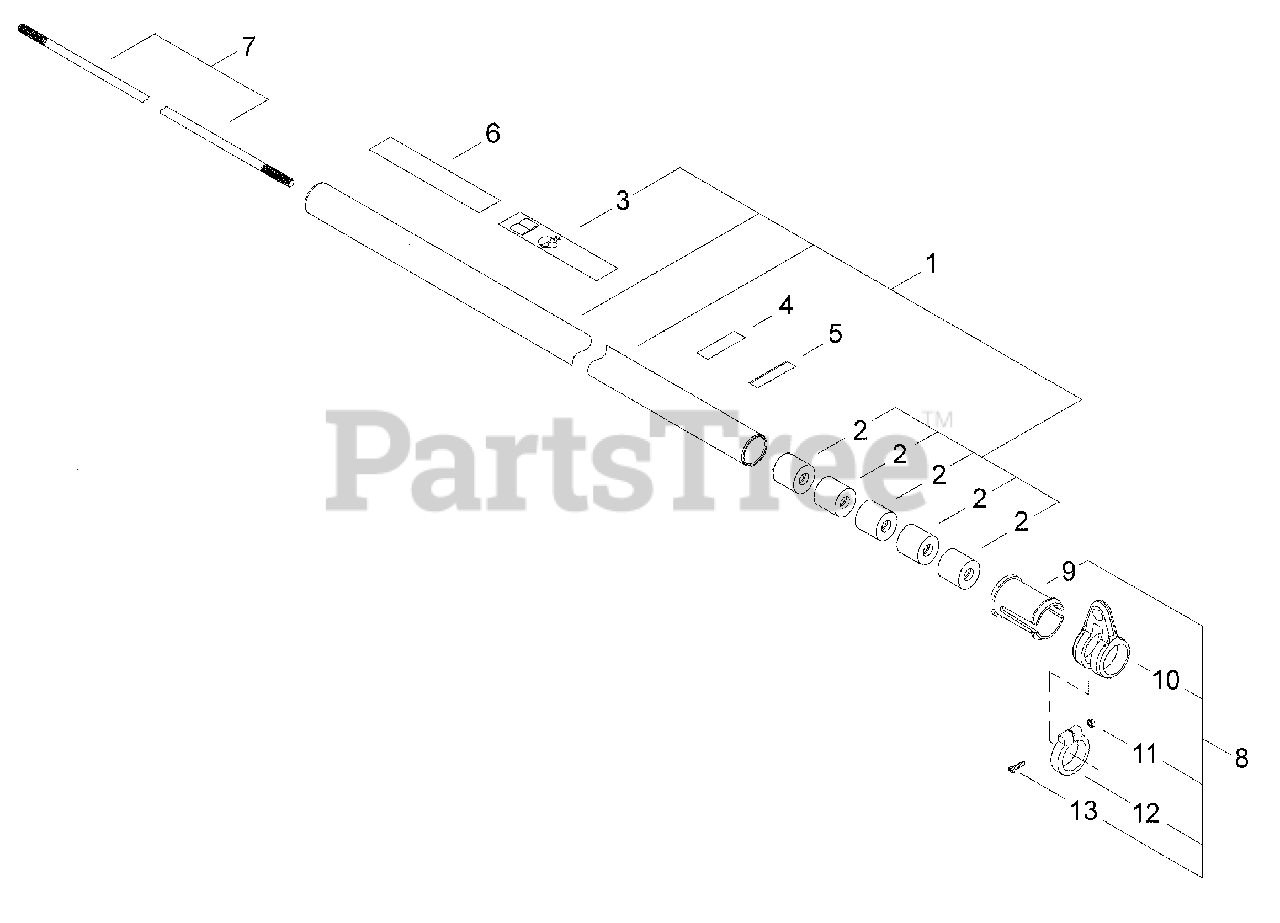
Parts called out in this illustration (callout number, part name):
2	BUSHING
3	LABEL, CAUTION (BLADE CAPABLE)
4	LABEL, HANDLE
5	LABEL - ALIGNMENT
6	LABEL, SWISHER E4
7	MAINSHAFT
8	HANGER ASSY
9	COLLAR 24
10	HANGER
11	NUT M4
12	CLAMP
13	SCREW M4×16
